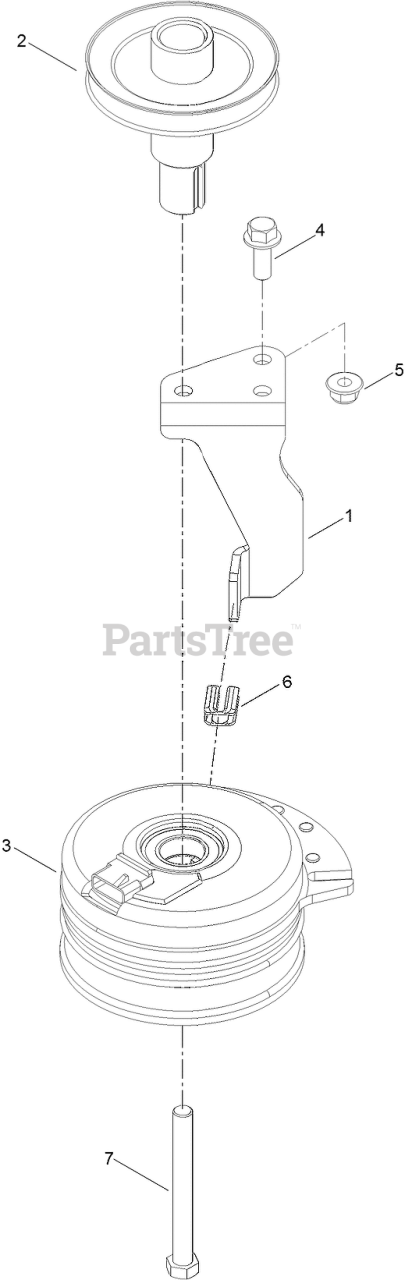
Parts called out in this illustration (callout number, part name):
1	STOP - CLUTCH (NARROW)
2	PULLEY-ENGINE
3	CLUTCH-ELECTRIC
4	SCREW-HHF
5	NUT-HF, NI
6	ISOLATOR-CLUTCH
7	SCREW-HH
